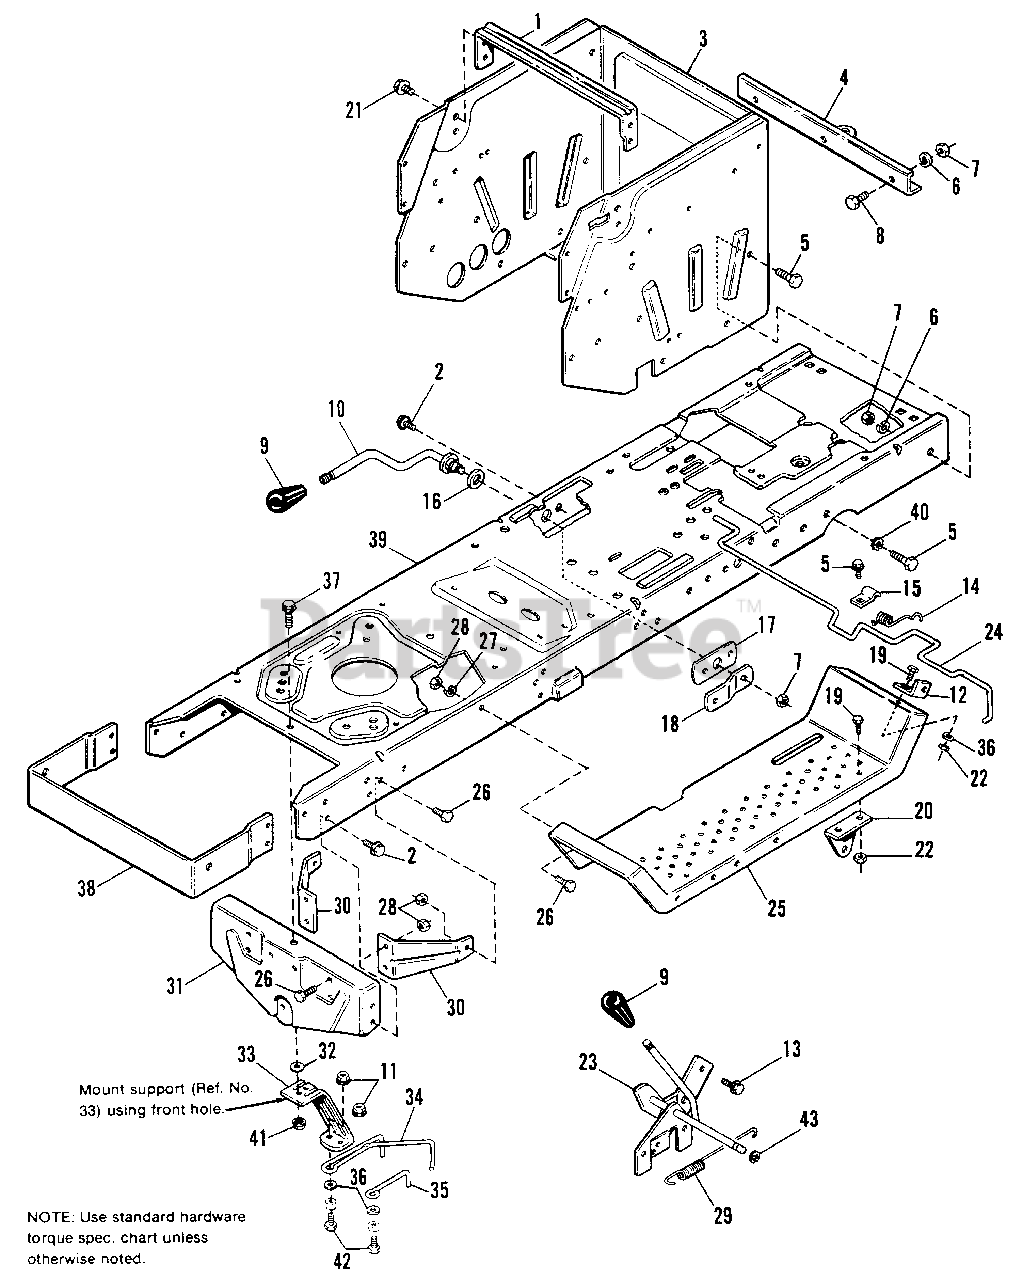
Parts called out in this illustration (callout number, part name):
1	BRACE, Seat
2	SCREW, Taptite, 5/16-18 x 3/4
3	SUPPORT, Axle Wrapper
4	BAR, Draw
5	CAPSCREW, Hex, 3/8-16 x 1, Gr. 5
6	LOCKWASHER, 3/8
7	NUT, Hex, 3/8-16
8	CAPSCREW, Hex, 3/8-16 x 1
9	GRIP, Handle
10	HANDLE, Lift
11	NUT, Hex, Lock, Flange 5/16
12	BRACKET, Seat Latch
13	SCREW, Taptite, 1/4-20 x 1/2
14	SPRING, Torsion
15	CLIP, Latch Rod
16	WASHER, Nylon
17	BAR, Support
18	ARM, Support
19	CAPSCREW, Hex, 1/4-20 x 5/8
20	SUPPORT, Clutch
21	SCREW, Taptite, 5/16-18 x 1/2
22	NUT, Hex, 1/4-20
23	LEVER ASSY., Clutch
24	ROD, Latch
26	CAPSCREW, Hex, 5/16-18 x 3/4
27	LOCKWASHER, 5/16
28	NUT, Hex, 5/16-18
29	SPRING, Extension
30	BRACE, Axle Support
31	SUPPORT, Axle
32	WASHER, Plain, 11/32-1 x 10 Ga.
36	WASHER, 1/4
37	CAPSCREW, Hex Flange Whizlock, 5/16-18 x 1-1/4
40	LOCKWASHER, Ext. 3,8 (Zinc Pltd.)
41	NUT, Hex, Flange, Whizlock, 5/16-18
42	CAPSCREW, 5/16-18 x 7/8
43	RING, Retaining, 1/2
